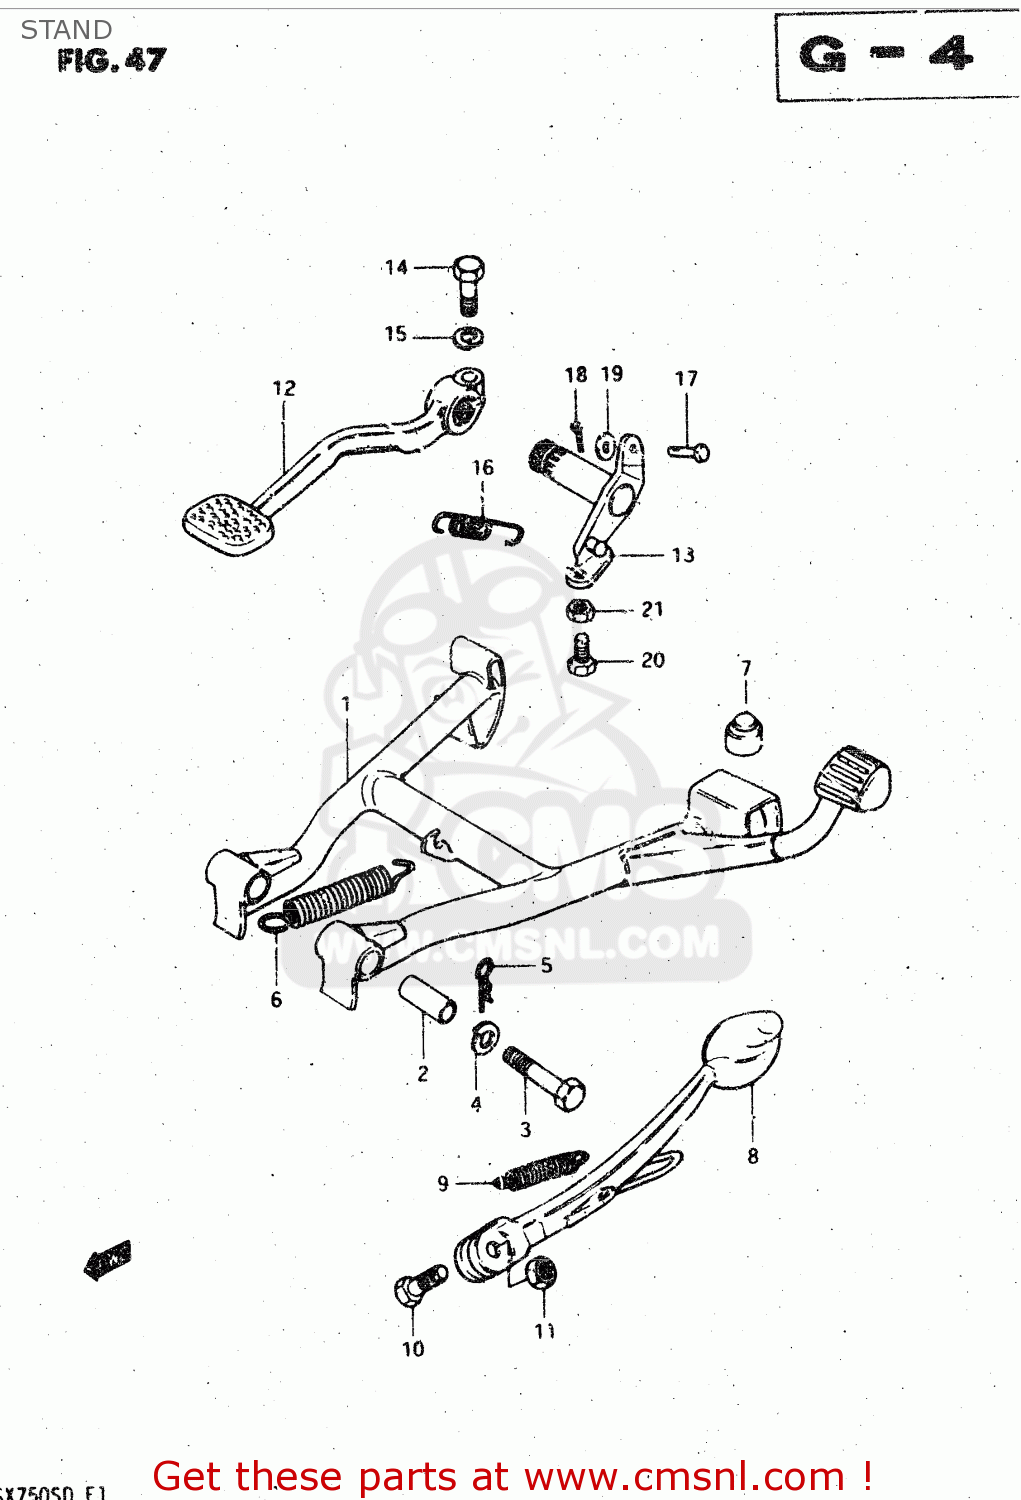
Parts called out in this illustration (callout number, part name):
1	STAND,CENTER
2	SPACER(10X16X38.8)
3	BOLT
4	LOCK WASHER
5	CLIP
6	SPRING
7	CUSHION
8	STAND,PROP
9	SPRING
10	BOLT(10X30)
11	NUT
12	PEDAL,BRAKE
13	ARM,BRAKE PEDAL
14	BOLT
15	LOCK WASHER
16	SPRING
17	PIN
18	PIN
19	WASHER
20	BOLT
21	NUT
